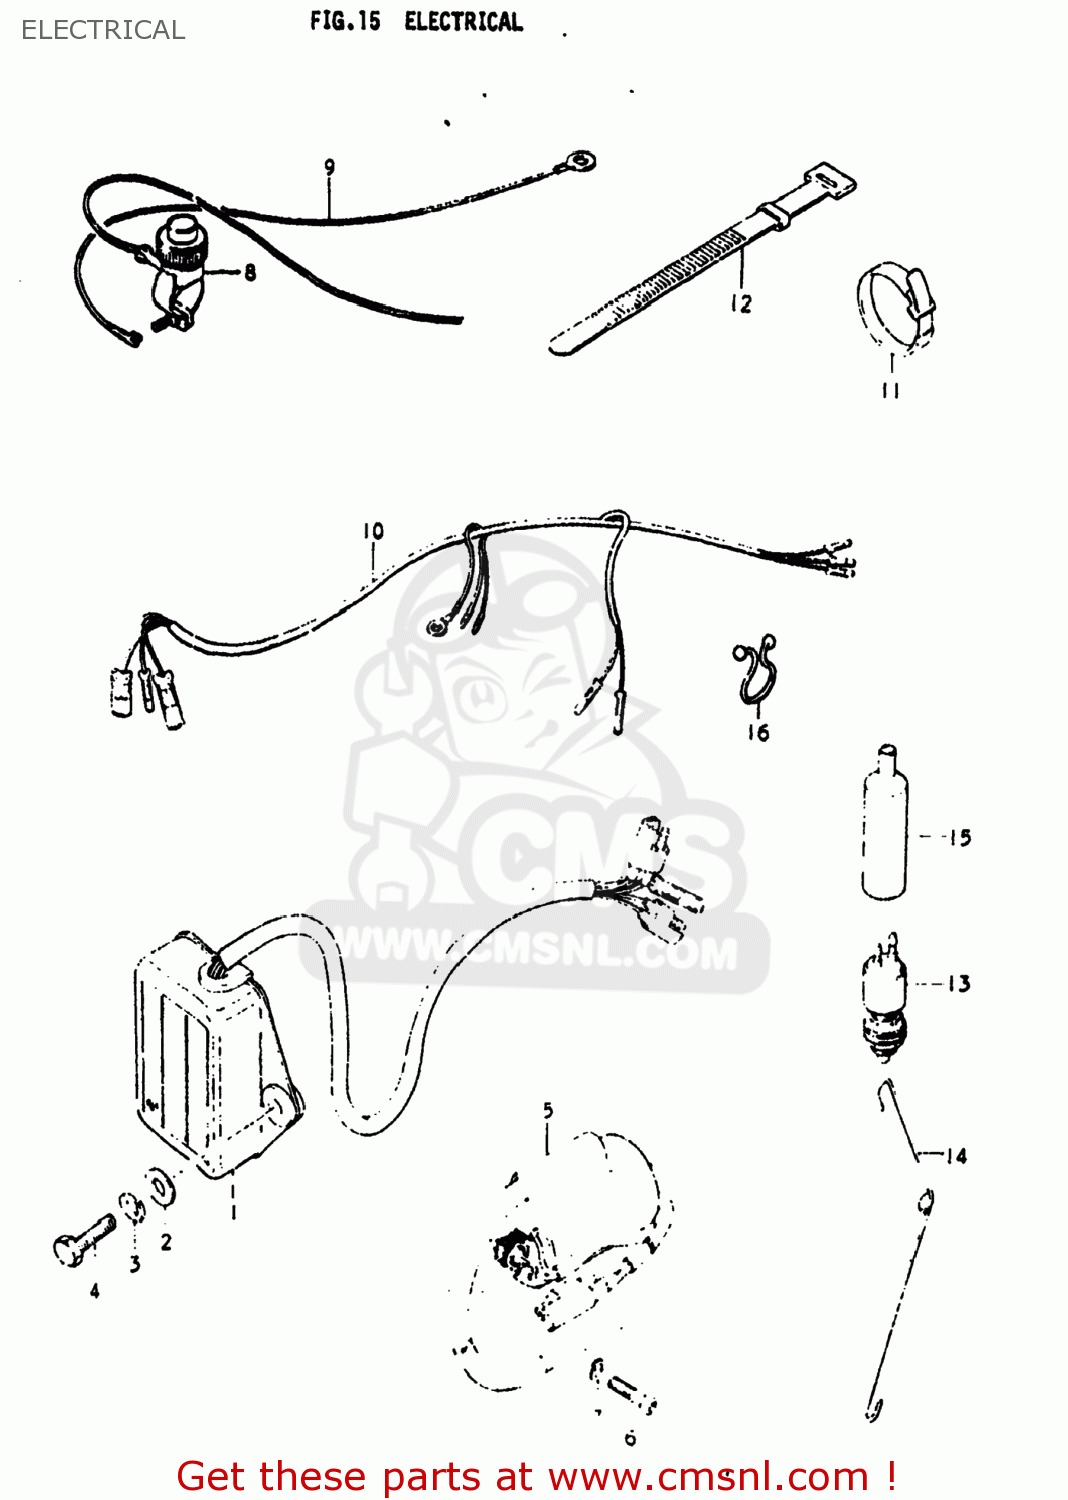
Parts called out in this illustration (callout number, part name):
1	CDI UNIT ASSEMBLY
2	WASHER(6.5X16X1.2)
3	LOCK WASHER
4	BOLT
5	COIL ASSEMBLY,IGNITION
6	SCREW 5X20
7	LOCK WASHER
8	SWITCH ASSEMBLY
9	WIRE
10	HARNESS,WIRING
11	CLAMP
12	CLAMP(L:120)
13	SWITCH ASSY,BRAKE LAMP
14	SPRING
15	BOOT,WIRING HARNESS
16	CLIP(ID:11.5)
